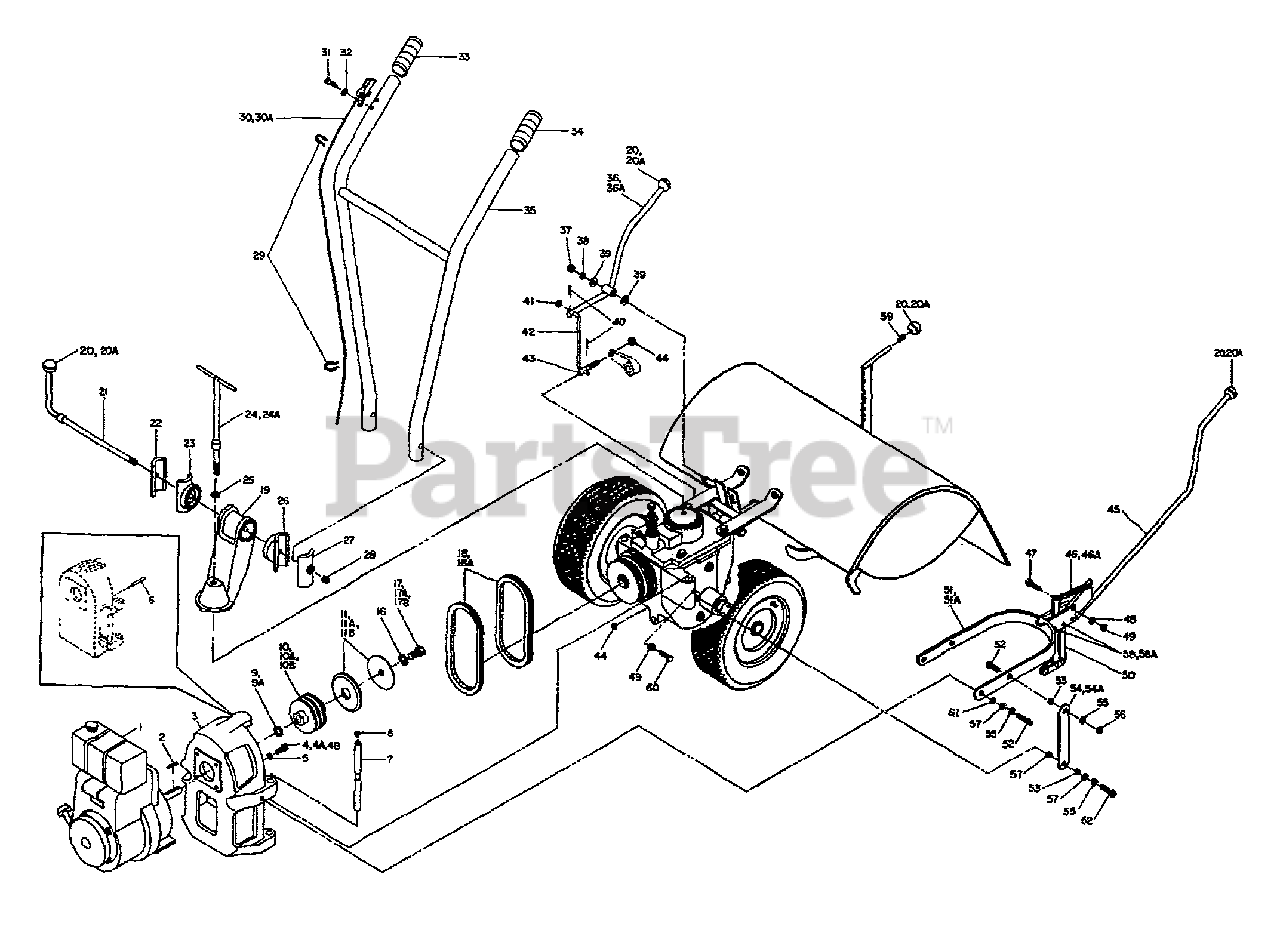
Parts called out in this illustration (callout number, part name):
1	ENGINE
2	KEY-.188 SQ X 2.33
3	MOUNT-MOTOR ENG.HSE I,II,III
4	SCR 5/16-24 X 1
4A	SCR-HH 5/16-18X1.0 G5 ZP
4B	SCR 5/16-24 X 1
5	WASHER-LK .312 ZP
6	PIN-SPIROL .25 X 2.5
7	BAR-ENG MTG W/CAP PLUG
8	PLUG-CAP (RED)
9	SHIM-1.0X.7656X.062
9	SHIM-1.0X.7656X.031
9A	SHIM-1.0X.7656X.062
10	PULLEY-ENG MACH
10A	PULLEY-ENG MACH D/BELT
10B	KIT-PULLEY CONVERSION
11	KIT-ADJ BLOCK/REV DISC
11A	KIT-REV DISC 2 SPEED
11B	KIT-REV DISC 2 SPEED
16	WASHER-LK .375 @ DEPL
17	SCR-HH 3/8-24X1.75 ZP
17A	SCR-HH 3/8-24X1.5 G5
17B	BOLT-HH 5/16-24 X 1.5 ZP
18	BELT-V
18A	KIT-V BELT
19	KIT-BASE ASSM
20	KNOB-CONTROL
20A	KNOB-THREADED
21	STUD-H/BAR W/NUT & RING
22	CLAMP-RH HORSE 1021-2
23	RATCHET-RT H/BAR CAST
24	T-CLAMP WELD
24A	SCR-5/8 (2373/1043)
25	WASHER-LK .625 ZP
26	RATCHET-LT H/BAR CAST
27	CLAMP-LH HORSE 1021-1
28	NUT-HEX JAM 1/2-13
29	TIE-RED
30	CABLE-THROTTLE
30A	CABLE-THROTTLE
31	SCR-PHS M10-32X.5 STH ZP
32	WASHER-LK M10
33	GRIP-H/BAR SMOOTH
34	GRIP-HANDLEBAR
35	ASSM-HANDLEBAR
36	LEVER-SPD SHIFT W/KNOB
36A	LEVER-WHL SPEED W/KNOB
37	NUT-H/LK 1/2-20 ZP
38	WASHER-LK .5
39	WASHER-PLAIN 1/2 ZP
40	PIN-COTTER .094X1.0
41	WASHER-FLAT 5/16 SAE
42	ROD-CONNECTING
43	SWIVEL
44	NUT-H/LK 5/16-18
45	TRAC-RER
46	SPRING-.436 X 3.25
46A	SPRING-.406 X 3.125
47	SCR-HH 5/16-18X1.25 G5ZP
48	WASHER-LK .312 ZP
49	NUT-HEX 5/16-18 ZP
50	KIT-ROLLER HORSE 1 & 2
51	KIT-LEVER FWD/REV-HORSE 2
51A	YOKE-2SP WELD PNT
52	SCR-HH 3/8-16X1.0 G5 ZP
53	BUSHING-.5X.375X.3
54	BAR-CLUTCH YOKE
54A	LINK-CLUTCH YOKE
55	WASHER-LK .375 @ DEPL
56	NUT-HEX 3/8-16 ZP
57	WASHER-FLAT 3/8 SAE
58	PIN-SPIROL .313 X 1.0
58A	TRACTOR-R.E.R. 11HP 36"
59	RING-TOLERANCE .5325 ID
60	SCR-HH 5/16-18X1.0 G5 ZP
61	BUSHING-.5X.375X.325
